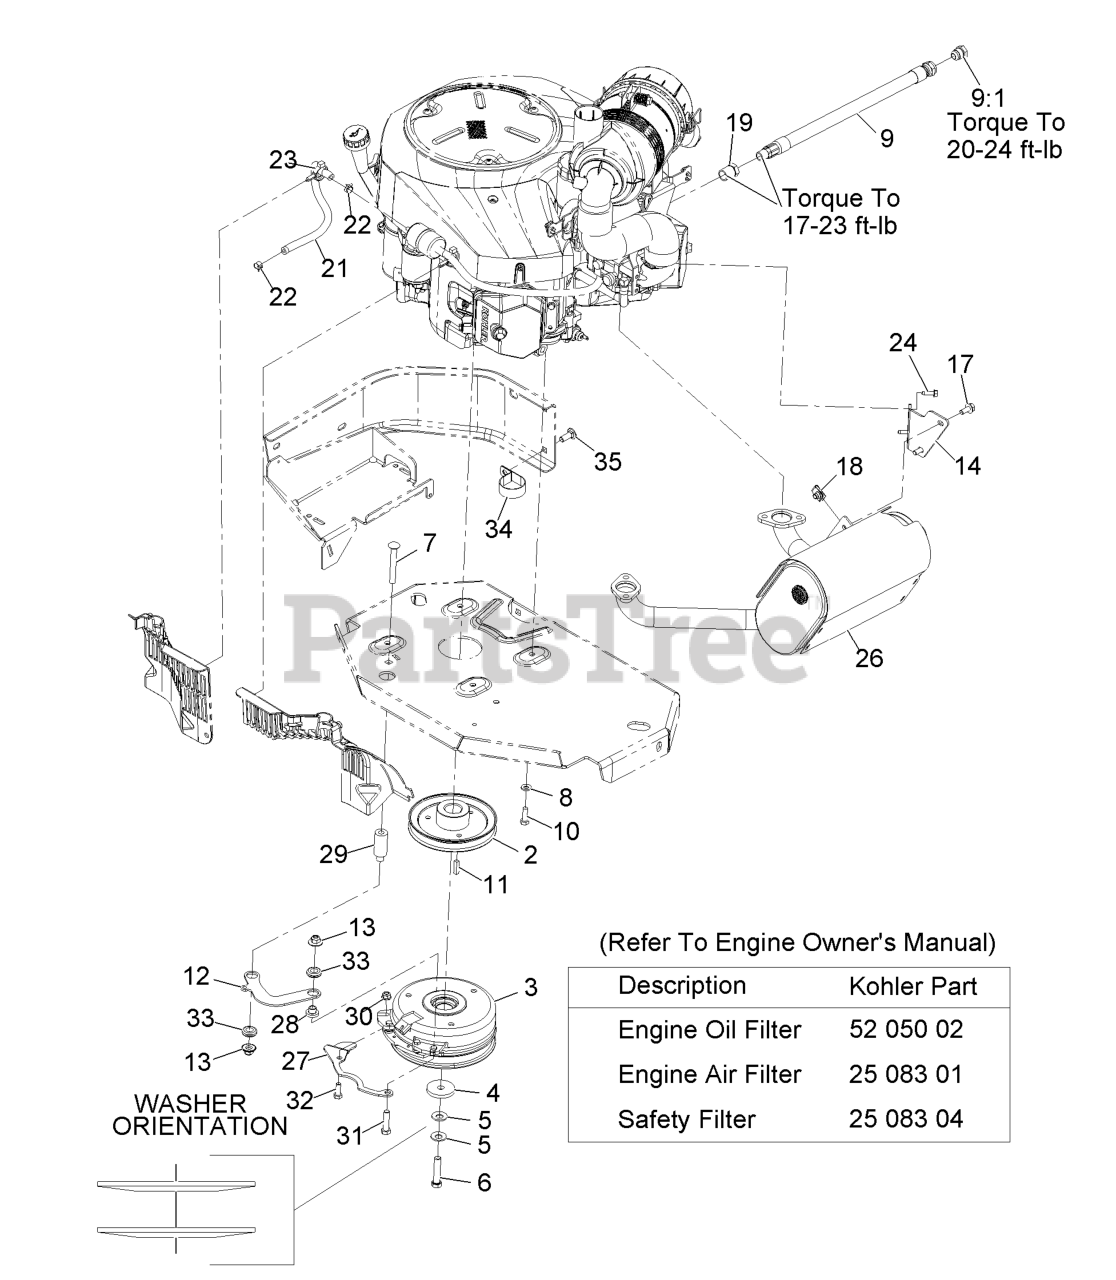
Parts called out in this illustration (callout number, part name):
2	SHEAVE
4	WASHER-CLUTCH
5	WASHER-SPRING
6	SCREW-HH W/LOCTITE
7	SCREW-CARR
8	WASHER-SPRING
10	SCREW-HH
12	LINK-ANCHOR, CLUTCH
13	Nut-Nyloc 3/8-16 Flg
17	SCREW-HHF
19	BUSHING
22	CLAMP-HOSE
23	CLAMP-HOSE
26	MUFFLER
27	BELT-GUIDE
30	NUT-HF, NI
31	SCREW-HH
32	SCREW-HH
33	GROMMET-RUBBER
34	CLAMP-R
35	SCREW-CARR
